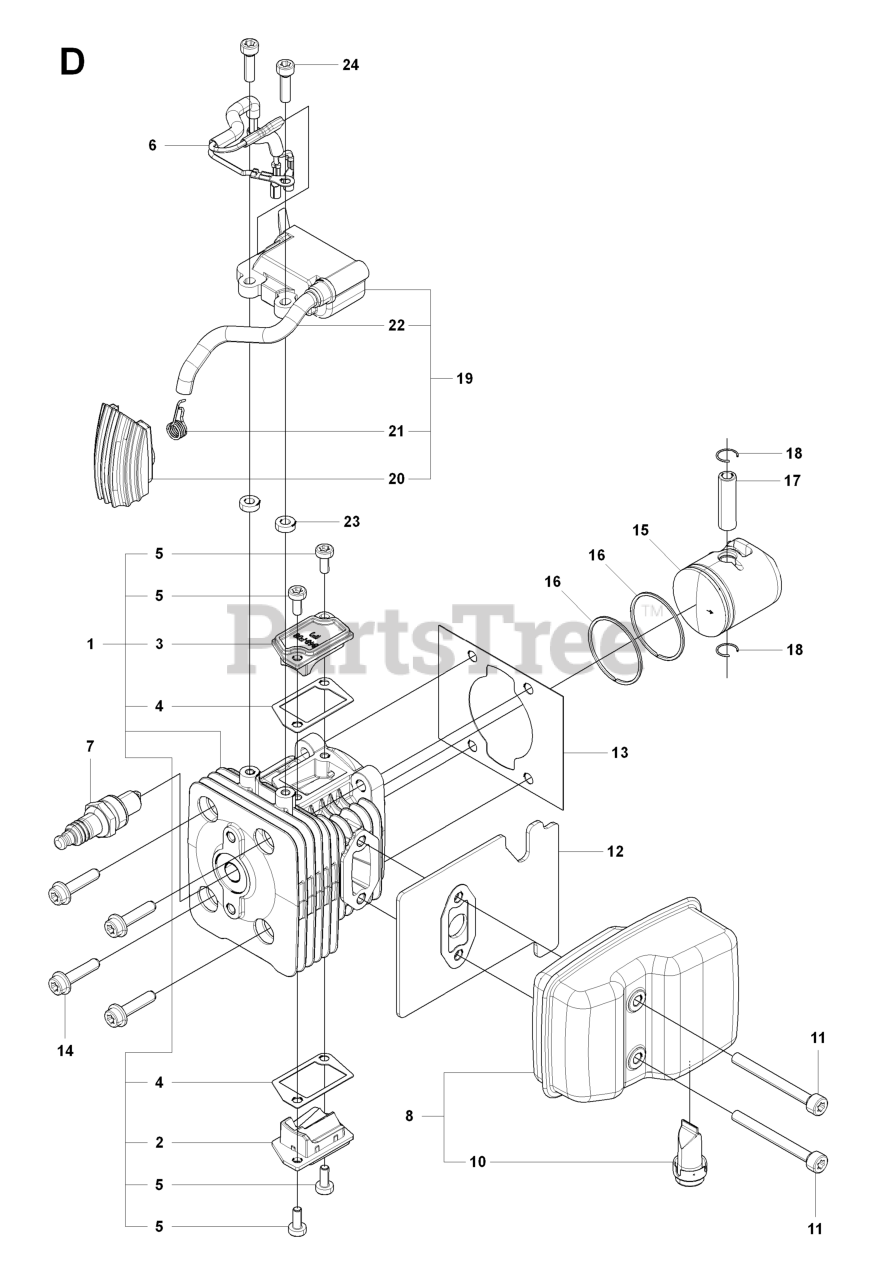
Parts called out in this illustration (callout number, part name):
1	CYLINDER COMPLETE
2	COVER, TR-S
3	COVER, TR-F
4	GASKET, TR
5	BOLT
7	SPARK PLUG NGK CMR7H
11	BOLT TORX M5XL50 T27
13	GASKET, BASE
14	BOLT TORX
17	PIN
18	RING
19	COIL ASSY
20	CAP
23	SPACER
24	BOLT TORX M4XL16 T27
